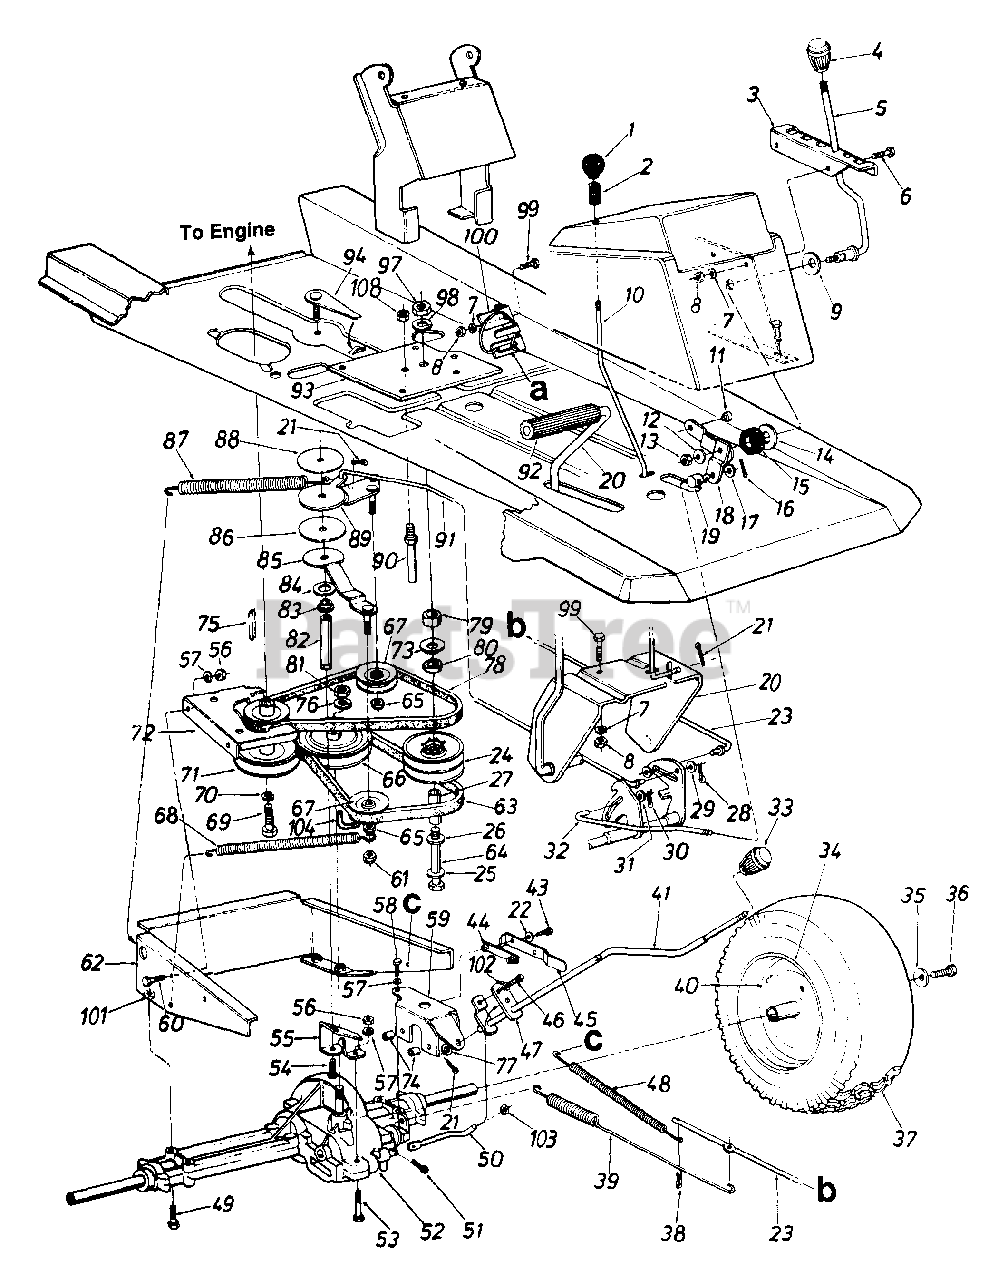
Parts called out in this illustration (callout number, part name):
1	Ball Knob 1/4-20 Thd. 1.25"
2	Compression Spring
5	Speed Control Lever
6	Truss Mach. Scr. 5/16-18 x .75" Lg.
7	L-Wash. 5/16" I.D.
8	Hex Nut 5/16-18 Thd.
9	Bell-Wash. .345" I.D. x .88"
10	Brake Locking Rod
12	Bell-Wash. .345" I.D. x .08"
13	Hex Cent. L-Nut 5/16-18 Thd.
14	Fl-Wash. .50" I.D. x 1.5" O.D.
15	Rubber Washer
16	Intern. Cotter Pin 1/2" Dia.
17	Fl-Wash. .34" I.D. x .68" O.D.
18	Speed Control Lever Brkt. Ass'y.
19	Ferrule - Engagement
20	Clutch/Brake Pedal Ass'y.
21	Cotter Pin 3/32" Dia. x .75"
22	Plastic Washer
24	Variable Speed Pulley Ass'y.
25	Fl-Wash. .4" I.D. x 1.25" O.D.
26	Thrust Brg. 1.25" O.D. x .56" I.D.
27	Spacer Sleeve 2.71"
28	Cotter Pin 1/8" Dia. x 1.25"
29	Fl-Wash. .34" I.D. x .60" O.D.
30	Intern. Cot-Pin 5/16" Dia.
31	Fl-Wash. .34" I.D. x .60" O.D.
32	Speed Control Rod
33	Shift Knob
35	Bell-Wash. .345" I.D. x .88"
36	Hex L-Bolt 5/16-24 x .75" Lg.
38	Cotter Pin 1/8" Dia. x 1.25"
39	Extension Spring 17.0" Lg.
40	Air Valve
44	Insulator Nut
45	Spring Switch
46	Hex Bolt 1/4-20 x .50" Lg.
47	Shift Lever Adjusting Link
48	Ext. Spring 8-1/4" Lg.
49	Hex Bolt 5/16-18 x 2.5" Lg.
51	Intern. Cotter Pin
52	Transaxle
53	Hex Bolt 1/4-20 x 1.75" Lg.
54	Hex Bolt 3/8-24 x .75" Lg.
57	L-Wash. 1/4" I.D.
58	Self-Tap Mach. Scr. Type "C" 1/4-20 x 1.37" Lg.
59	Shift Lever Support Brkt.
60	Hex Bolt 1/4-20 x 1.00" Lg.
61	Hex L-Nut 3/8-24 Thd.
64	Hex Bolt 3/8-16 x 4.5" Lg.
65	Hex Ins. L-Nut 3/8-24 Thd.
67	V-Belt Idler .38" I.D. x 3.06"
68	Ext. Spring .50" O.D. x 6.37"
69	Hex Bolt 7/16-20 x 1.00" Lg.
70	L-Wash. 7/16" I.D.
71	Engine Pulley
72	Upper Eng. Belt Guard
73	Bell-Wash. .4" I.D. x 1.12" O.D.
74	Spacer .256" I.D. x .50" O.D.
75	Sq.-Key 1/4" x 2.00" Lg.
76	Bell-Wash. .567" I.D. x 1.125"
77	Fl-Wash. .469" I.D. x .88" O.D.
78	V-Belt
79	Spacer 1.00" x .380" O.D.
80	Thrust Wash. .56" I.D. x 1.25" O.D.
81	Hex Jam Nut 9/16-18 Thd.
83	Flange Bearing .378
84	Fl-Wash. .640" I.D. x 1.24"
85	Idler Bracket Ass'y.
86	Thrust Wash. .635" I.D.
87	Extension Spring 7.58" Lg.
88	Thrust Wash. .385" I.D.
89	Idler Bracket Ass'y. For Clutch
90	Belt Guard Pin 3/8-16 x 2.75" Lg.
92	Foot Pad
98	L-Wash. 3/8 Heavy Duty
99	Hex Bolt 5/16-18 x .75" Lg.
100	Speed Control Rod Brkt.
101	Hex Sems Nut 5/16-18 Thd.
102	Bell-Wash. .265" I.D. x .75" O.D.
103	Push On Retaining Ring
108	Hex Top L-Jam Nut 3/8-16 Thd.
